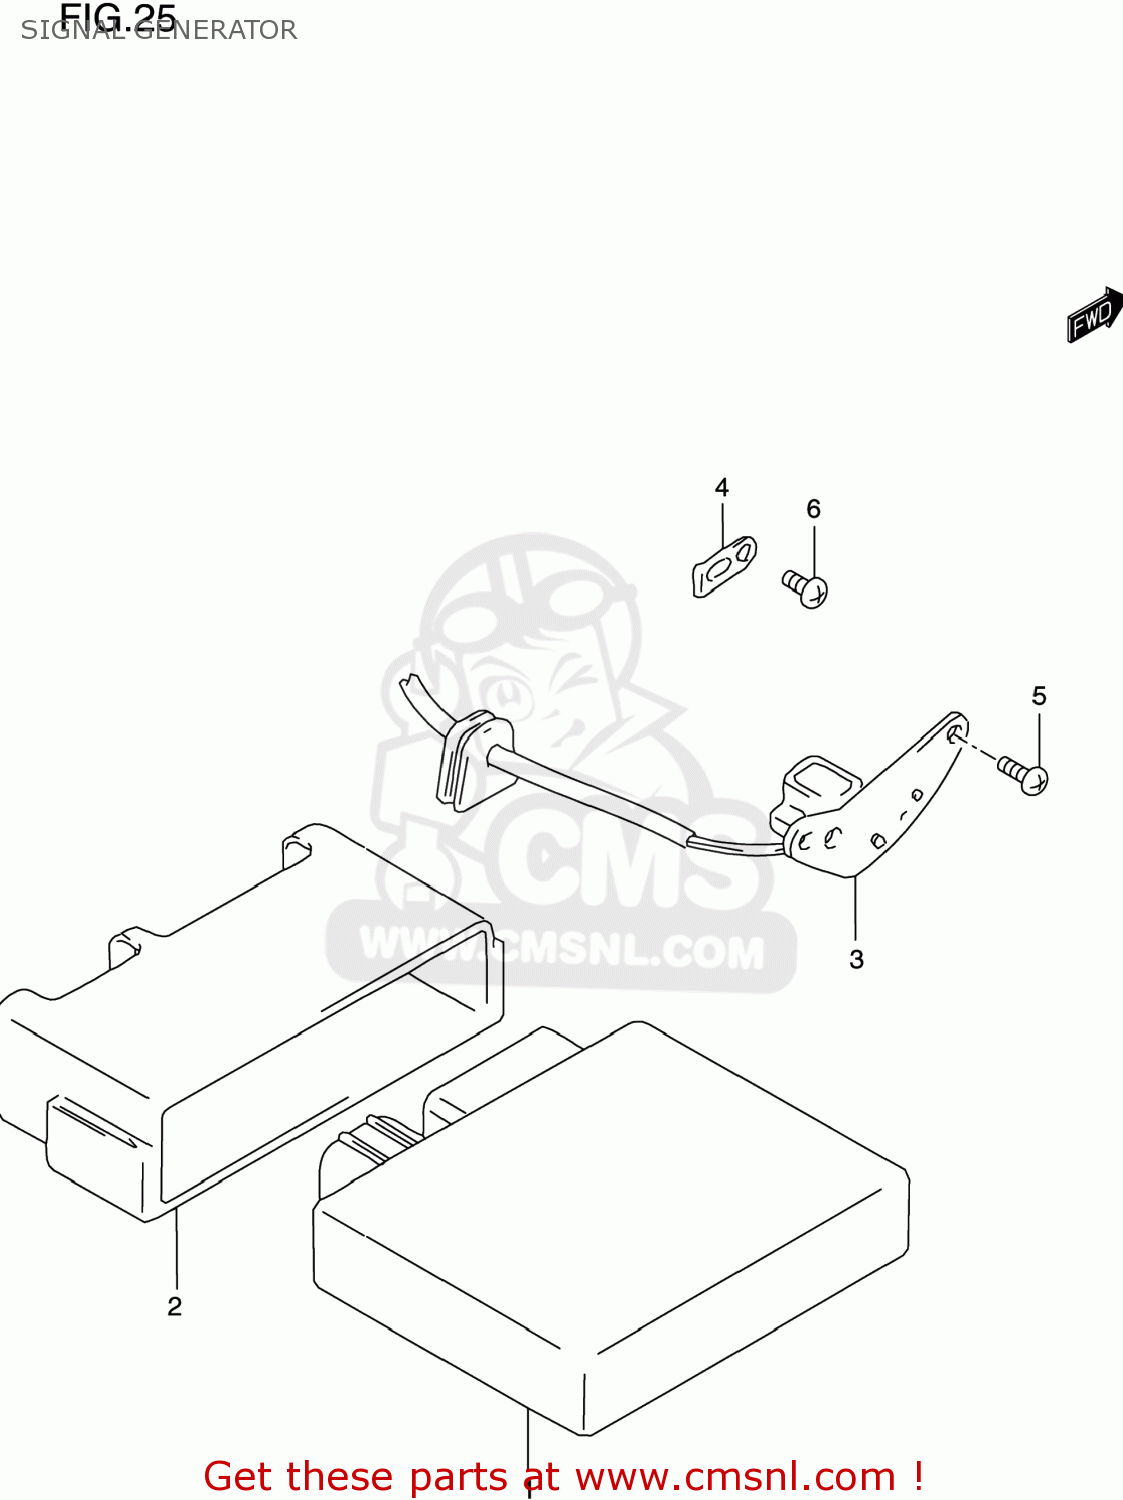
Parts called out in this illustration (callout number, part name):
1	CDI UNIT
2	CUSHION,IGNITER
3	STARTER,SIGNAL GENERATOR
4	CLAMP,SIGNAL GENERATORERATOR
5	SCREW
6	SCREW
